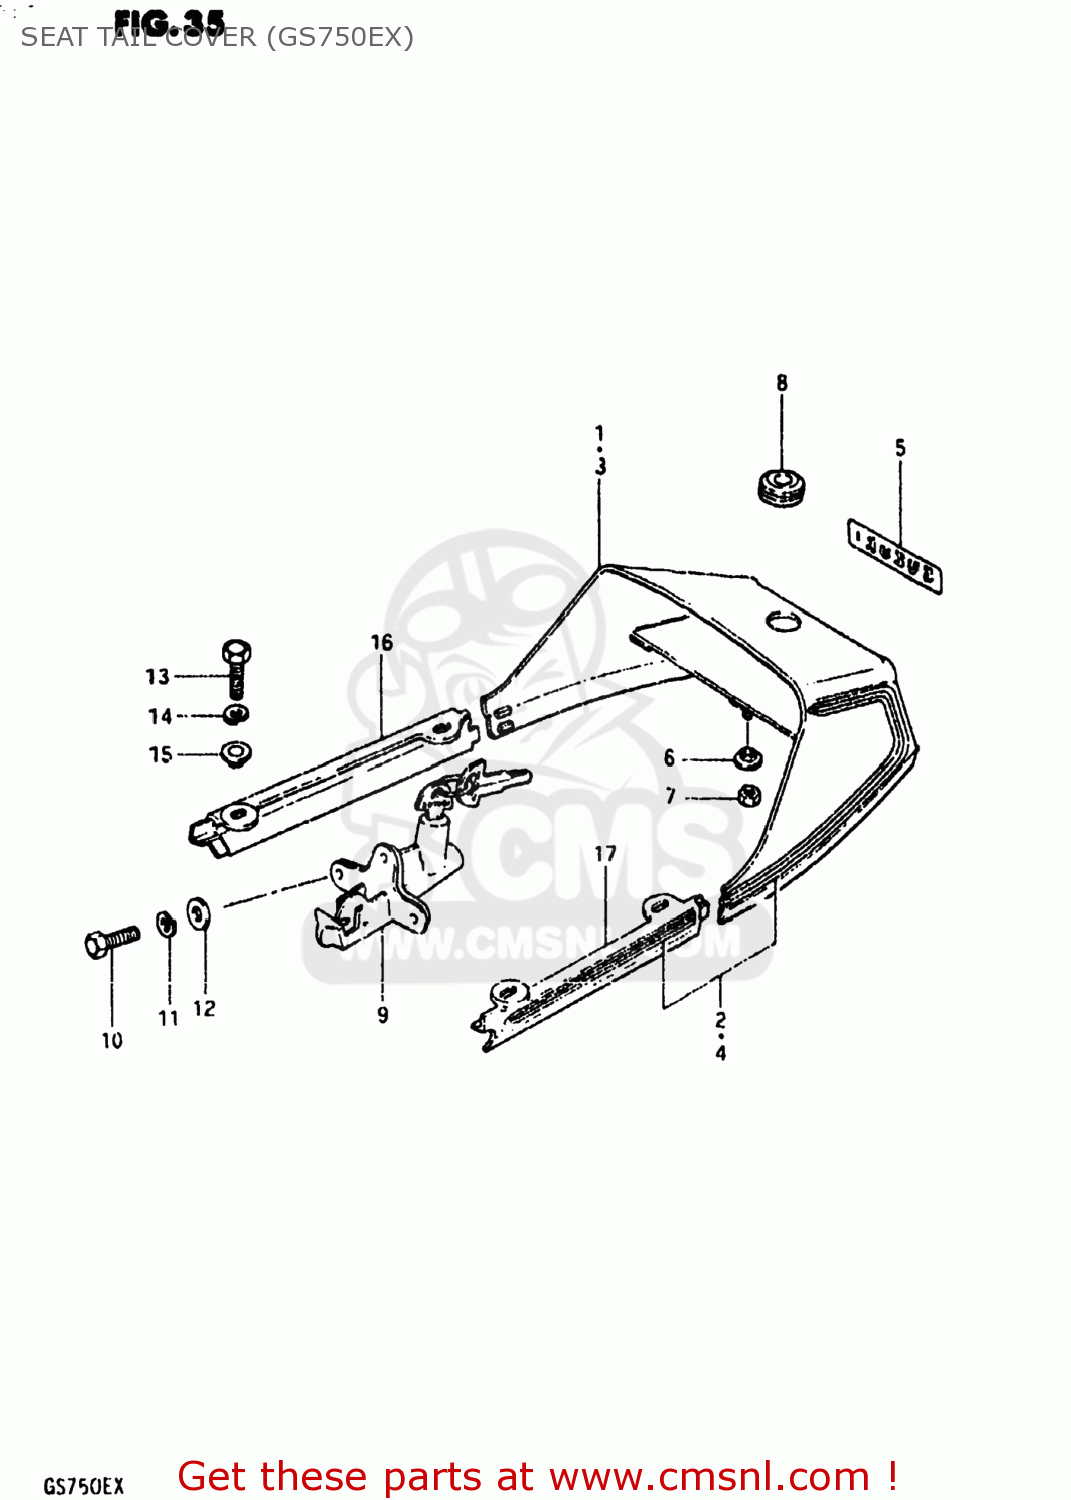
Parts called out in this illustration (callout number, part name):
1	BOX SET,SEAT TAIL
2	TAPE SET,SEAT TAIL COVER
3	BOX SET,SEAT TAIL
4	TAPE SET,SEAT TAIL COVER
5	EMBLEM (GOLD/BLACK)
6	WASHER
7	NUT 6MM
8	GROMMET,SEAT LOCK HOLE
9	LOCK SET,SEAT
10	BOLT
11	LOCK WASHER
12	WASHER 6MM
13	BOLT
14	LOCK WASHER
15	WASHER
16	MOLDING,SEAT
17	MOLDING,SEAT
